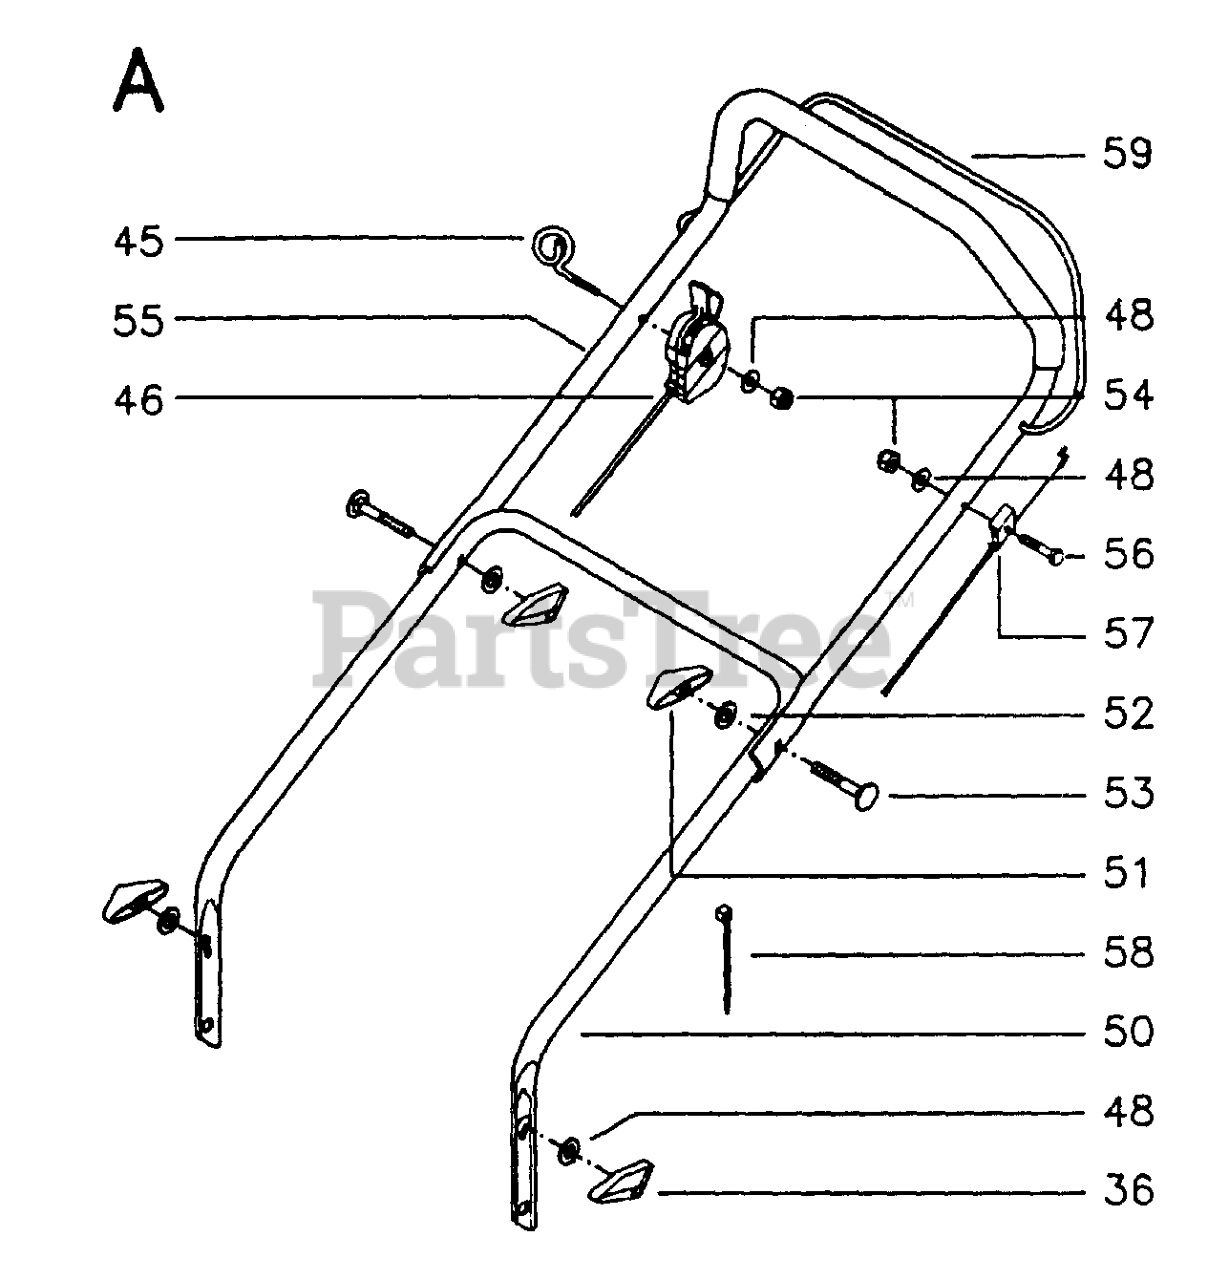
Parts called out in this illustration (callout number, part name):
36	REPL BY 732 21 16-01
46	THROTTLE TRIGGER
51	WINGNUT
52	WASHER - 15X7.3X1.6
54	LOCKNUT M6
56	BOLT FLANGE
57	CONTROL CABLE
